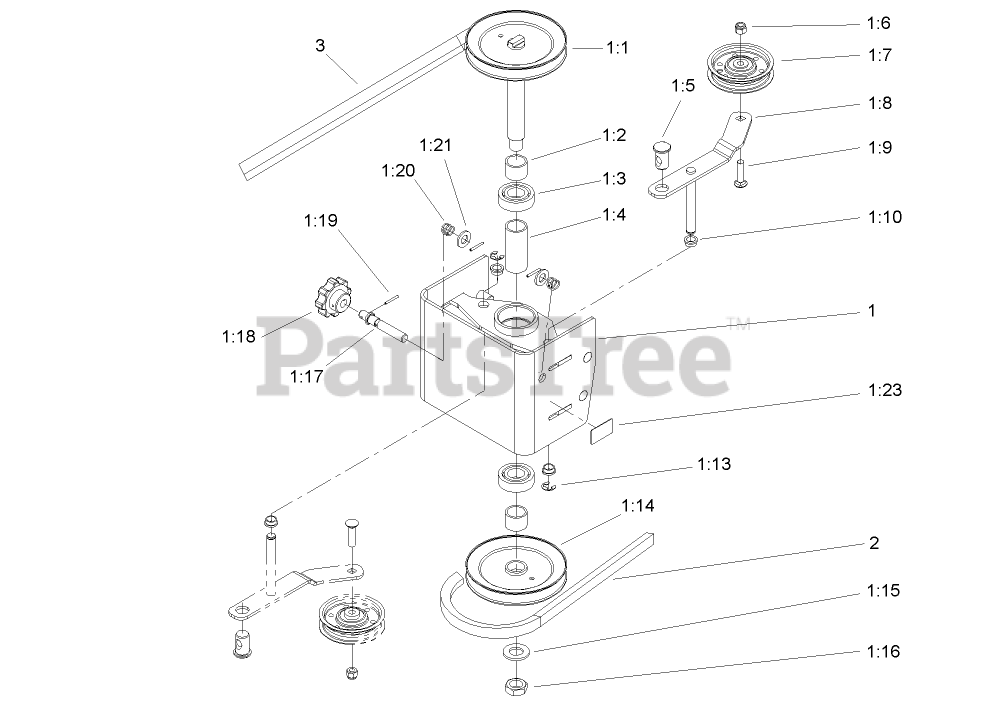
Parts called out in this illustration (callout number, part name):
1	PULLEY BOX ASM
1:1	UPPER PULLEY ASM
1:2	SPACER-PULLEY
1:3	BEARING-BALL
1:4	SPACER-BEARING
1:5	FERRULE-ADJUSTER
1:7	PULLEY-IDLER, FLAT
1:8	IDLER ARM ASM
1:9	SCREW-CARR
1:10	BUSHING-FLANGE
1:13	RING-RETAINING, EXTERNAL
1:15	WASHER-FLAT
1:16	NUT-JAM
1:17	ROD-TENSION
1:19	PIN-ROLL
1:20	SPRING-COMPRESSION
1:21	WASHER-FLAT
1:23	DECAL-SURFACE, HOT
2	BELT-DRIVE
3	BELT-PTO
